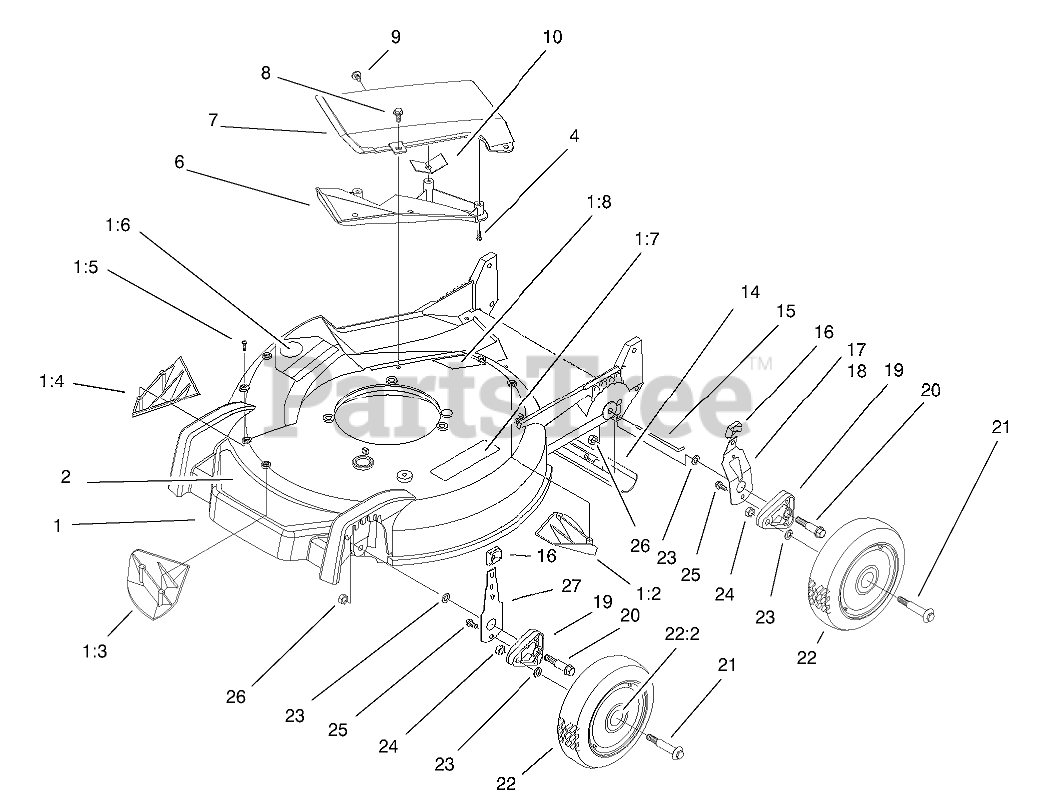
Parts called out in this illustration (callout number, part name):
1	HOUSING ASM
1:2	KICKER-REAR
1:3	KICKER-FRONT
1:4	KICKER-RH
1:5	SCREW-PPH
1:6	DECAL-DANGER
1:7	DECAL-WARNING
1:8	DECAL-WARNING
2	DECAL - DECK
4	Screw-PPH
6	Deflector
7	RECYCLER COVER ASM.
8	SCREW-HWH
9	SCREW AND WASHER ASM
10	Cover Guard
14	SHIELD-TRAILING
15	ROD-SHIELD
16	KNOB-ARM
17	LH SPRING ARM ASM
18	RH SPRING ARM ASM
19	ARM-PIVOT, FRONT
20	BOLT-SHOULDER
21	BOLT-SHOULDER
21	BOLT-WHEEL
22	WHEEL ASM
22	WHEEL AND TIRE ASM
22:2	BUSHING
23	WASHER
24	NUT-LOCK
25	SCREW-HWH
26	NUT-LOCK
27	FRONT SPRING ARM ASM
